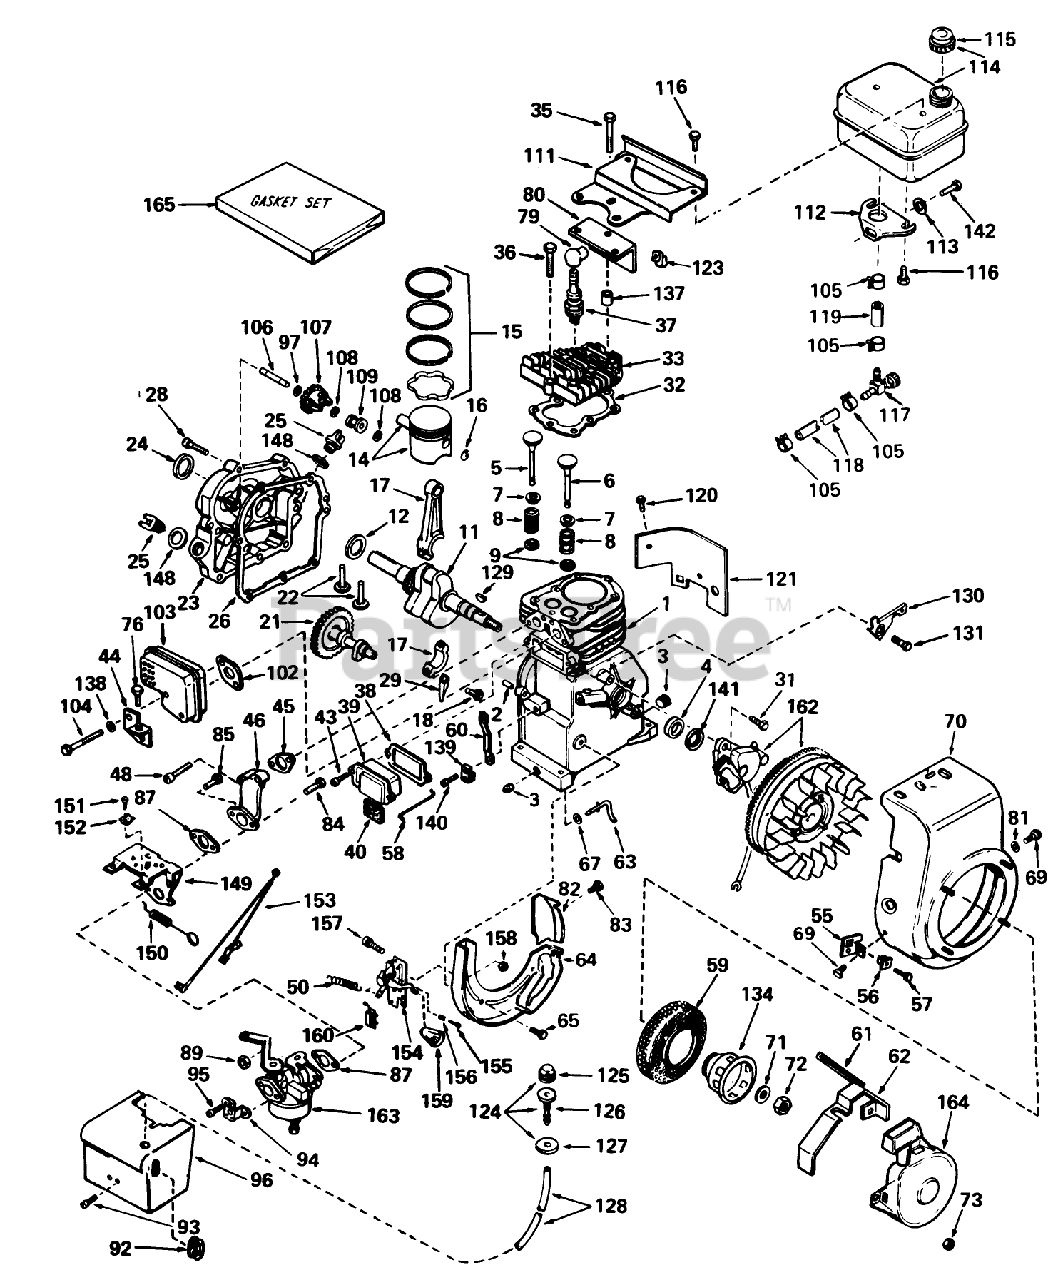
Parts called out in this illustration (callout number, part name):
1	Cylinder Assy. (Incl. #2, 3 & 4)
2	Pin-Dowel
3	Plug, Sq. Hd. Pipe, 1/4-18 (Oil Drain)
4	Seal-Oil
5	Valve, Intake (Std.) (Incl. #7, 8 & 9)
5	Valve, Intake (1/32 Oversize)(Inch. #7, 8 & 9)
6	Valve, Exhaust (Std.) (Incl. #7, 8 & 9)
6	Valve, Exhaust (1/32" Oversize) (Incl. #7, 8 & 9)
7	Cap-Upper Valve Spring
8	Spring-Valve
9	Cap-Valve, Spring
11	Crankshaft Assembly
12	Washer-Thrust
14	Piston, Pin & Ring Assy. (Incl. #15 & 16)(Std.)
14	Piston, Pin & Ring Assy. (Incl. #15 & 16) (.010 Oversize)
14	Piston, Pin & Ring Assy. (Incl. #15 & 16) (.020 Oversize)
15	Ring Set Piston (Std.)
15	Ring Set Piston (.010 Oversize)
15	Ring Set Piston (.020 Oversize)
16	Ring-Retaining, Piston Pin
17	Rod Assembly, Connecting (Incl. #18 & 29)
18	Bolt-Rod, Connecting
21	Camshaft
22	Lifter-Valve
23	Cover, Cylinder (Incl. #24, 25, 106 & 148)
24	Seal-Oil
25	Plug, Oil Filler (Incl. #148)
26	Gasket-Cylinder Cover
28	Screw
29	Dipper-Oil
32	63573 GIL 42 SNWTHW
33	Head Cylinder
35	Screw (5/16-18 X 2)
36	Screw (5/16-18x1-1/2)
37	Plug, Spark (J17LM or equiv.)
37	Plug, Spark (Champion RCJ-8)
38	Gasket Breather
39	Breather Assy. (Incl. #38 & 40)
40	Element-Breather
44	Bracket-Cover, Carburetor
45	Gasket, Intake
46	Pipe, Intake
48	Screw (1/4-20 x 1-19/32)
50	Spring-Extension
55	Bracket
56	Grommet
57	Screw
58	Link-Governor to Throttle
59	Screen-Starter
60	Lever, Governor
61	Seal, Snowguard
62	Guard-Starter
63	Rod-Governor
64	Baffle-Blower Housing
65	Screw (1/4-20x19/32)
67	Washer-Flat
69	Screw
70	Housing, Blower
71	Washer-Spring
72	Hex Nut
73	Nut and Lock Washer (1/4-28)
76	Screw (10-24 x 3/8)
79	Cover-Spark Plug
80	Baffle-Heat
82	Baffle-Extension
83	Screw-Hex Washer Hd.
84	Screw
85	Screw-Fil. Hd.
87	Gasket
89	Nut and Lock Washer (1/4-28)
92	Grommet, Carburetor cover
93	Screw (8-32 X 5/16)
94	Bracket-Choke
95	Screw (10-32 x 1/2)
96	Cover, Carburetor
97	Washer-Flat
102	Gasket-Intake
103	Muffler
104	Screw-Fil. Hd.
105	Clamp-Line, Fuel
106	Shaft-Governor
107	Gear Assy., Governor (Incl. #97)
108	Ring-Retaining
109	Spool-Governor
111	Plate-Fuel Tank
112	Bracket, Fuel Tank Lower
114	Tank Assembly, Fuel (Incl. #115 & 116)
115	Cap, Fuel
116	Screw (1/4-15x7/8)
117	Valve-Shut Off
118	Line-Fuel
119	Line-Fuel (8.62)
121	Extension-Blower
123	51004 GIL ROTARY TI
124	Primer, Assy. (Incl. #125, 126 & 127)
125	33164A GILO"HITCH A
126	Body Primer
127	Retainer, Primer Bulb
128	Beam Assy.
129	Key, FIywheel
130	Bracket-Hold Down
131	Screw, Hex Hd. w/Conical
134	Cup, Starter
139	Clamp-Lever, Governor
140	Screw, Hex Washer Hd.
141	Gasket Stator
142	Screw Assembly
148	Gasket
149	Bracket, Speed Control
150	51011/13 TILL.O/P'7
151	Screw (10-32 x 3/8)
152	Conduit
153	Wire-Ground
154	Control Assembly, Speed (Incl. #155 thru 158 & 160)
155	Screw, Fil. Hd.
156	Spring-Compression
158	Nut-Lock
159	Knob-Control
160	Terminal
163	Carburetor (Incl. 1 of #87)
164	Starter Assy., Rewind
165	Gasket
